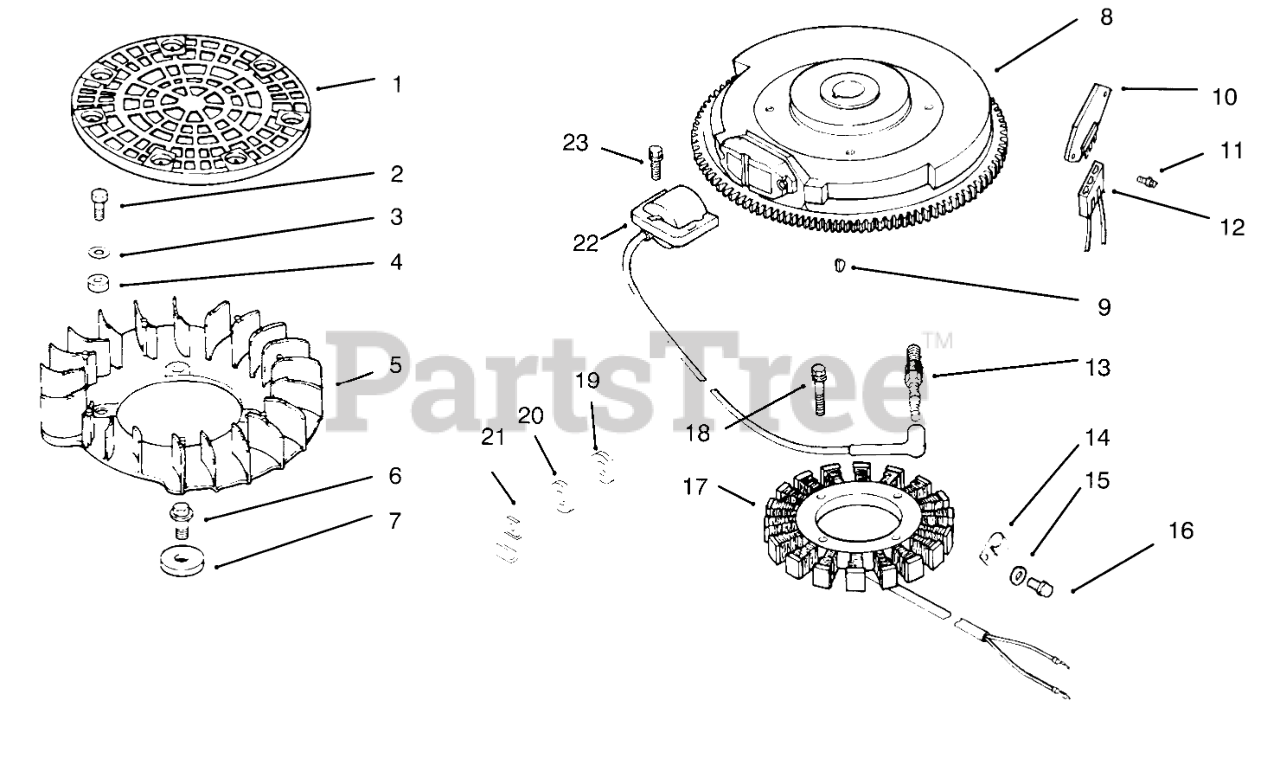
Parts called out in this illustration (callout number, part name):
1	Screen-Grass
3	Washer
4	Spacer-Fan
5	Fan
6	Screw
7	Spacer
8	Flywheel
9	Key
10	Rectifier-Regulator
11	Screw
12	Connector
13	Plug-Spark
14	Clip
15	Washer
16	Screw
17	Stator-15 Amp
18	Screw
19	Washer
20	Washer
21	Clip
22	Module-Ignition
